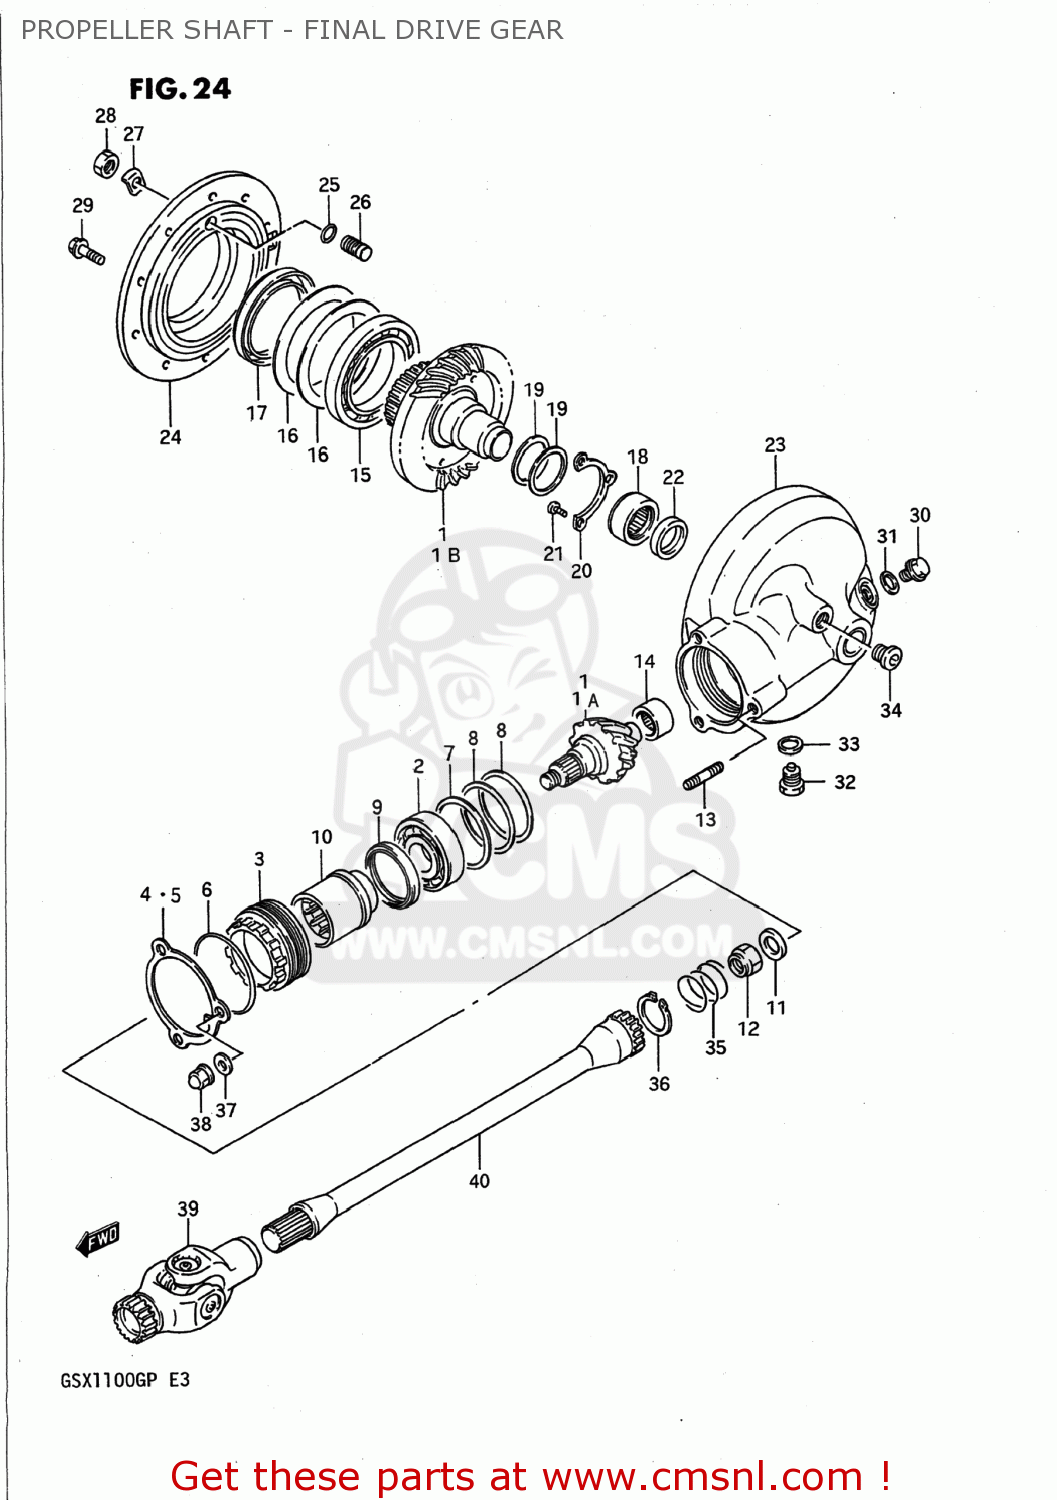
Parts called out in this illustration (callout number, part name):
1	GEAR & CASE SET,FINAL BEVEL
1A	GEAR,FINAL DRIVE BEVEL
1B	GEAR,FINAL DRIVEN BEVEL
2	BEARING(28X68X18)
3	STOPPER,FINAL DRIVE BEARING
4	PLATE,BEARING STOPPER
5	PLATE,BEARING STOPPER
6	O RING(D:3.1,ID:63.9)
7	WASHER(54X68X1.5)
8	SHIM,FINAL DRIVE GEAR 62
9	SEAL,OIL
10	COUPLING,FINAL DRIVE GEAR
11	WASHER(16X29X4)
12	NUT
13	STUD 10X25
14	BEARING(20X34X18)
15	BEARING(70X110X13)
16	SHIM,DRIVEN GEAR BEARING
17	SEAL,OIL(70X96X16)
18	BEARING(35X48X23.7)
19	SHIM,FINAL DRIVEN GEAR
20	RETAINER,FINAL DRIVEN GEAR BRG
21	SCREW 6X12
22	SEAL,OIL(30X42X7)
23	CASE COMP,FINAL GEAR
24	CASE,FINAL GEAR BEARING
25	O RING(D:1.9,ID:9.8)
26	BOLT,FINAL DRIVEN GEAR THRUST
27	WASHER (54X68X1.5)
28	NUT 12MM
29	BOLT 8X30
30	PLUG (14X12)
31	GASKET(14X19.2X2) (NAS)
32	PLUG
33	GASKET(14X19.2X2) (NAS)
34	PLUG
35	SPRING
36	CIRCLIP
37	WASHER
38	NUT
39	YOKE COMP,UNIVERSAL JOINT
40	SHAFT,PROPELLER
